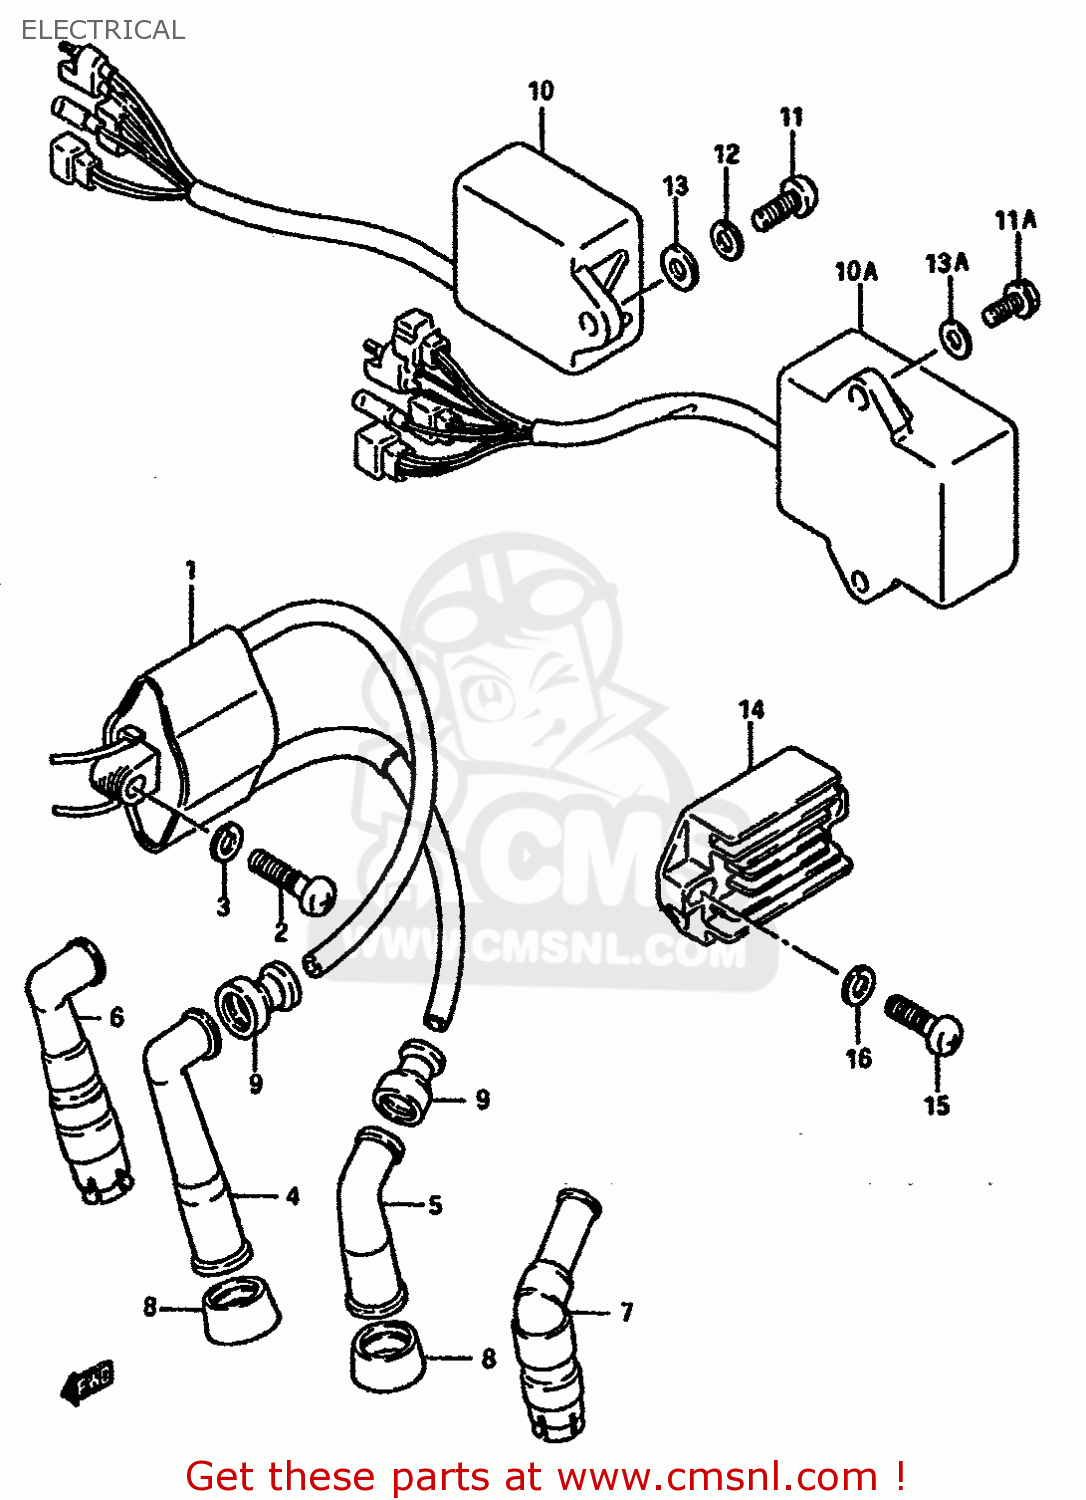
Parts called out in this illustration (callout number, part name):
1	COIL ASSEMBLY,IGNITION
2	SCREW
3	WASHER, LOWER
4	CAP ASSY,SPARK PLUG
5	CAP,SPARK PLUG
6	CAP, SPARK PLUG
7	CAP, SPARK PLUG
8	SEAL,SPARK PLUG CAP
9	SEAL,SPARK PLU
10	CDI UNIT
10A	CDI UNIT
11	SCREW
11A	SCREW
12	WASHER,LOCK
13	WASHER, LOWER
13A	WASHER
14	RECTIFIER ASSEMBLY
15	SCREW
16	WASHER,LOCK
